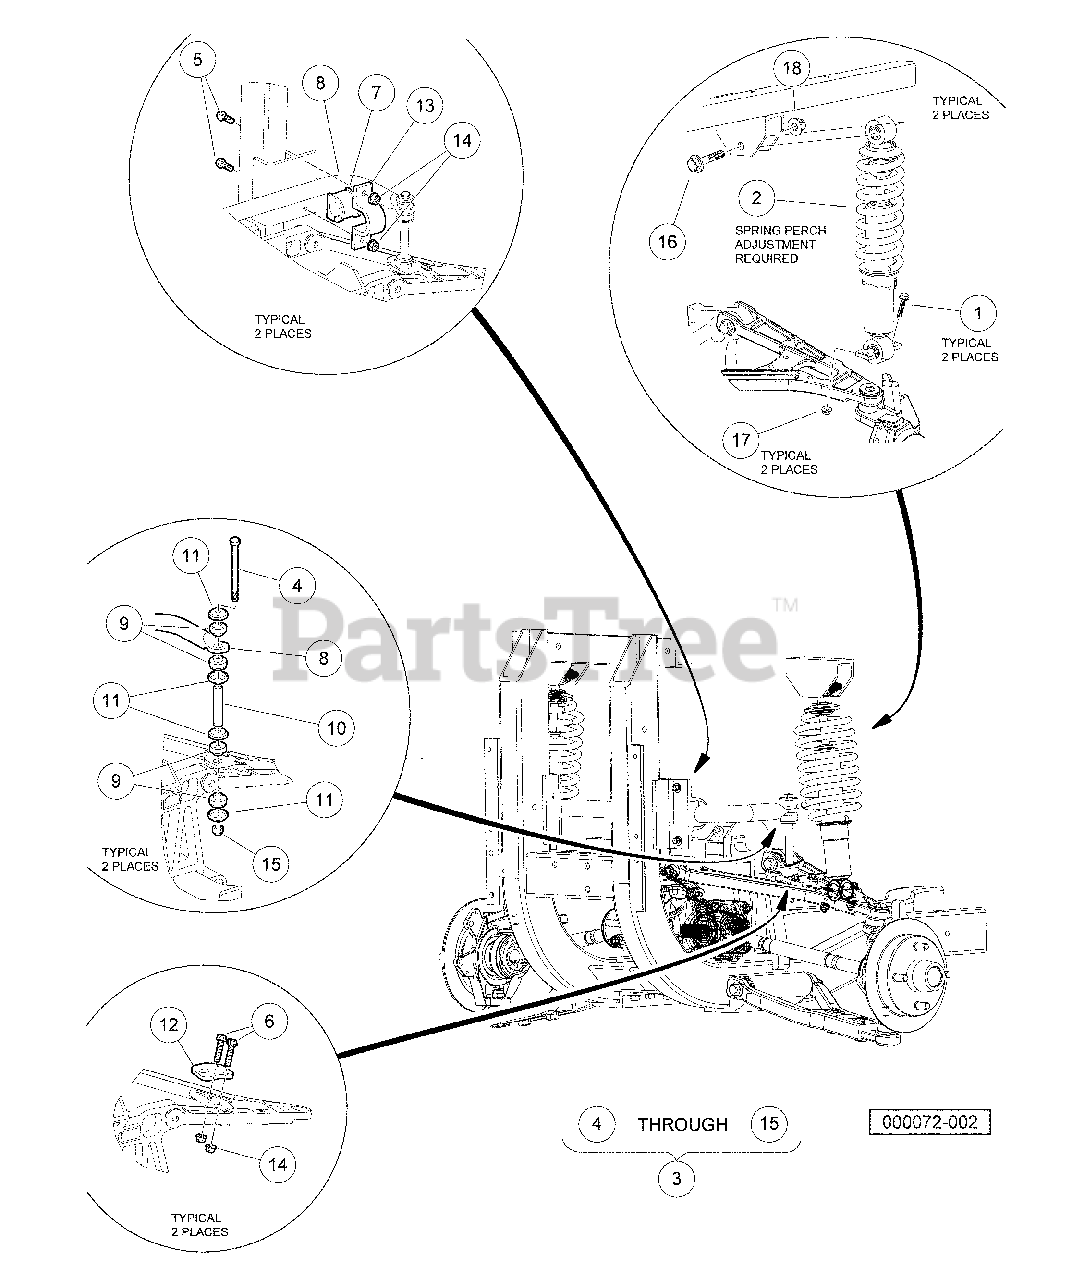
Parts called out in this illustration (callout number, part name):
1	Bolt, Flange Head, M8-1.25 X 40
2	Shock, Coil Over, Front Hd
3	Kit, Anti-Sway Bar
4	Screw, 3/8-16 X 7.00 Hex Cap
5	Bolt, Flange Head, M8 X 30.0
6	Bolt, Flange Head, M8-1.25 X 40
7	Bushing, Anti-Sway Bar, 1-1/8
8	Bar, Sway, Formed
9	Bushing, Link
10	Sleeve, Link
11	Washer, Cup, Bushing
12	Mount, Link
13	Bracket, Anti-Sway Bar
14	Lock Nut, Flg M8 X 1.25 Nylon
15	Locknut, 3/8-16 Hex
16	Bolt, Flange Head, M12 X 1.75 X 70
17	Lock Nut, Flg M8 X 1.25 Nylon
18	Nut Flg, M12x1.75, Nylon Gr 10
